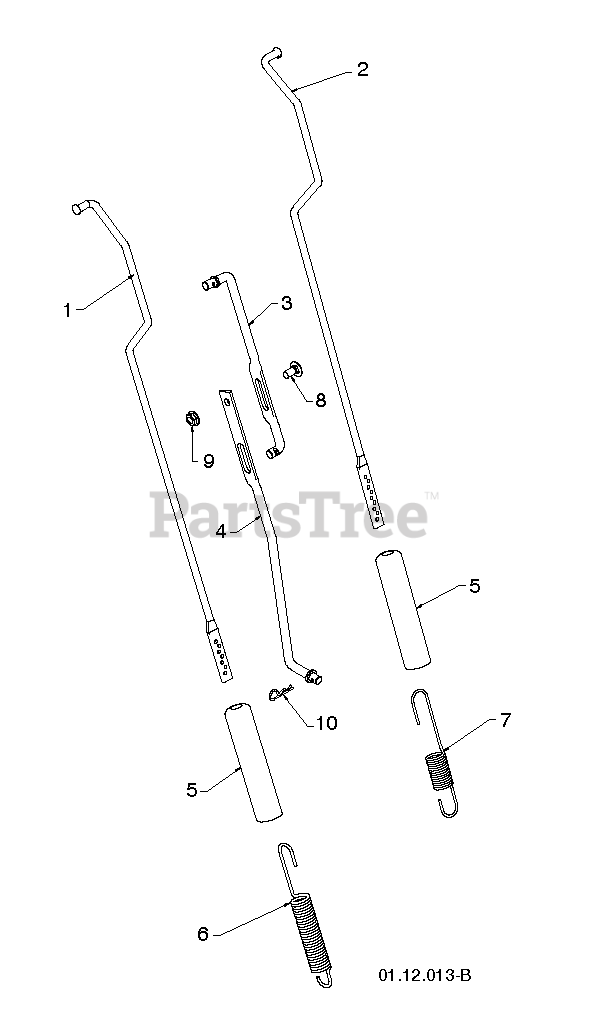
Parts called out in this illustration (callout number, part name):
1	ROD.IMPELLER
2	ROD.TRACTION
3	ROD, UPPER SPEED CONTROL
4	ROD, LOWER SPEED CONTROL
5	SLEEVE, SPRING
6	SPRING.CONTROL.ROD.SNOW
7	SPRING.TRACTION.ROD.SNOW
9	NUT.FLANGE.5/16
10	SPRING RETAINER
